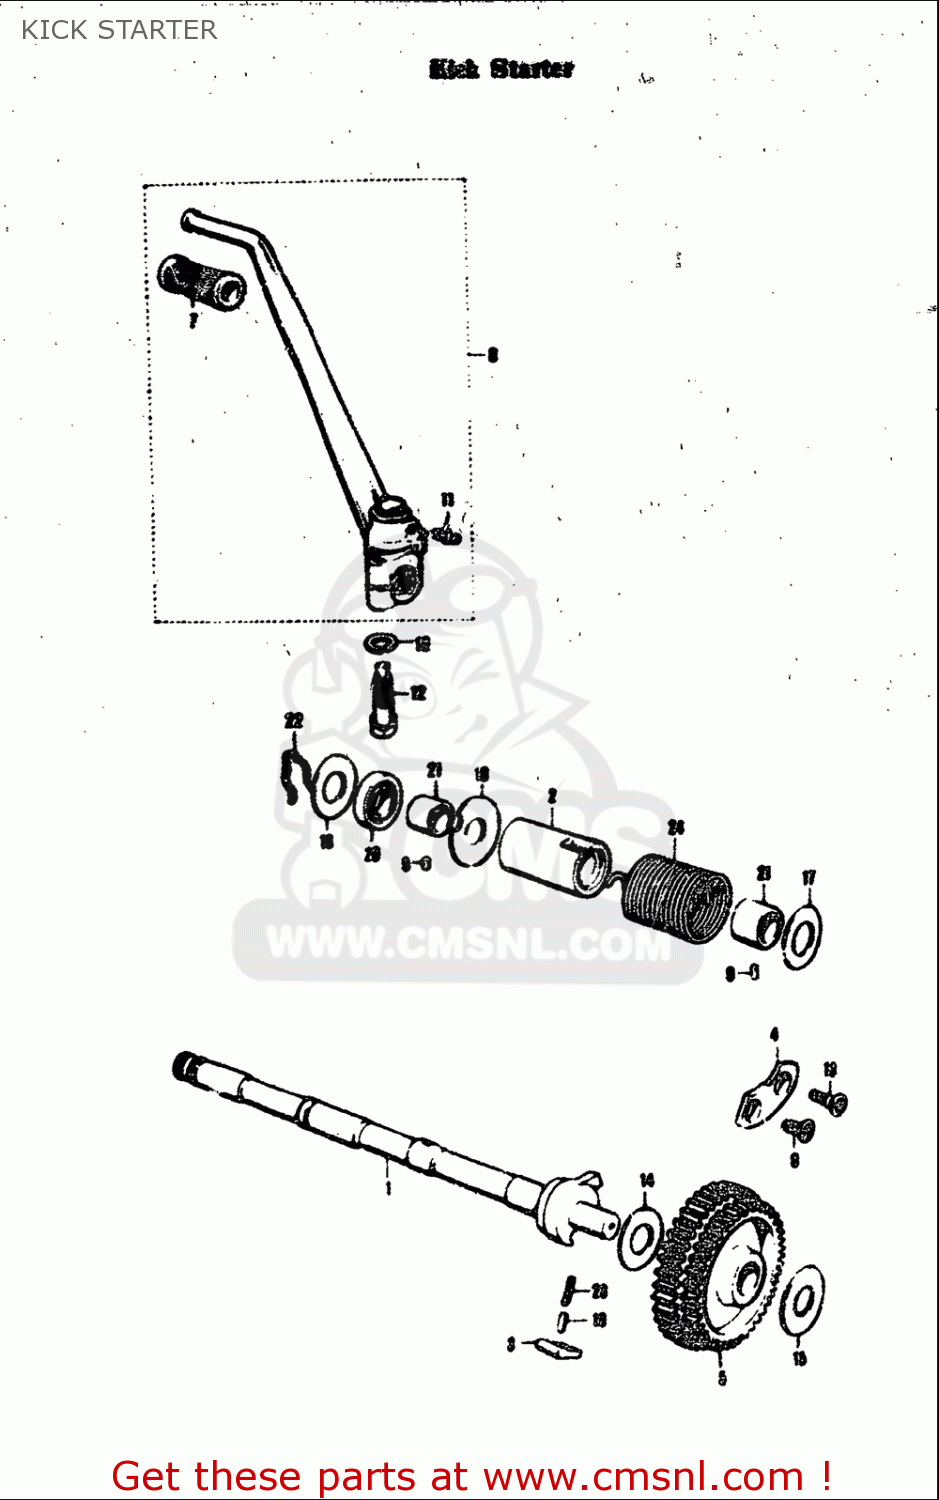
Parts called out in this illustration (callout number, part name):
7	RUBBER,KICK STARTER PEDAL
8	SCREW
9	PIN
10	WASHER,LOCK
11	NIPPLE
12	BOLT(10X37.5)
13	SCREW(6X19)
14	WASHER(13X31.5X1.5)
15	WASHER(13X31.5X1.5)
17	WASHER(16X30X1)
19	PIN(5X15.5)
23	SPRING
24	SPRING
